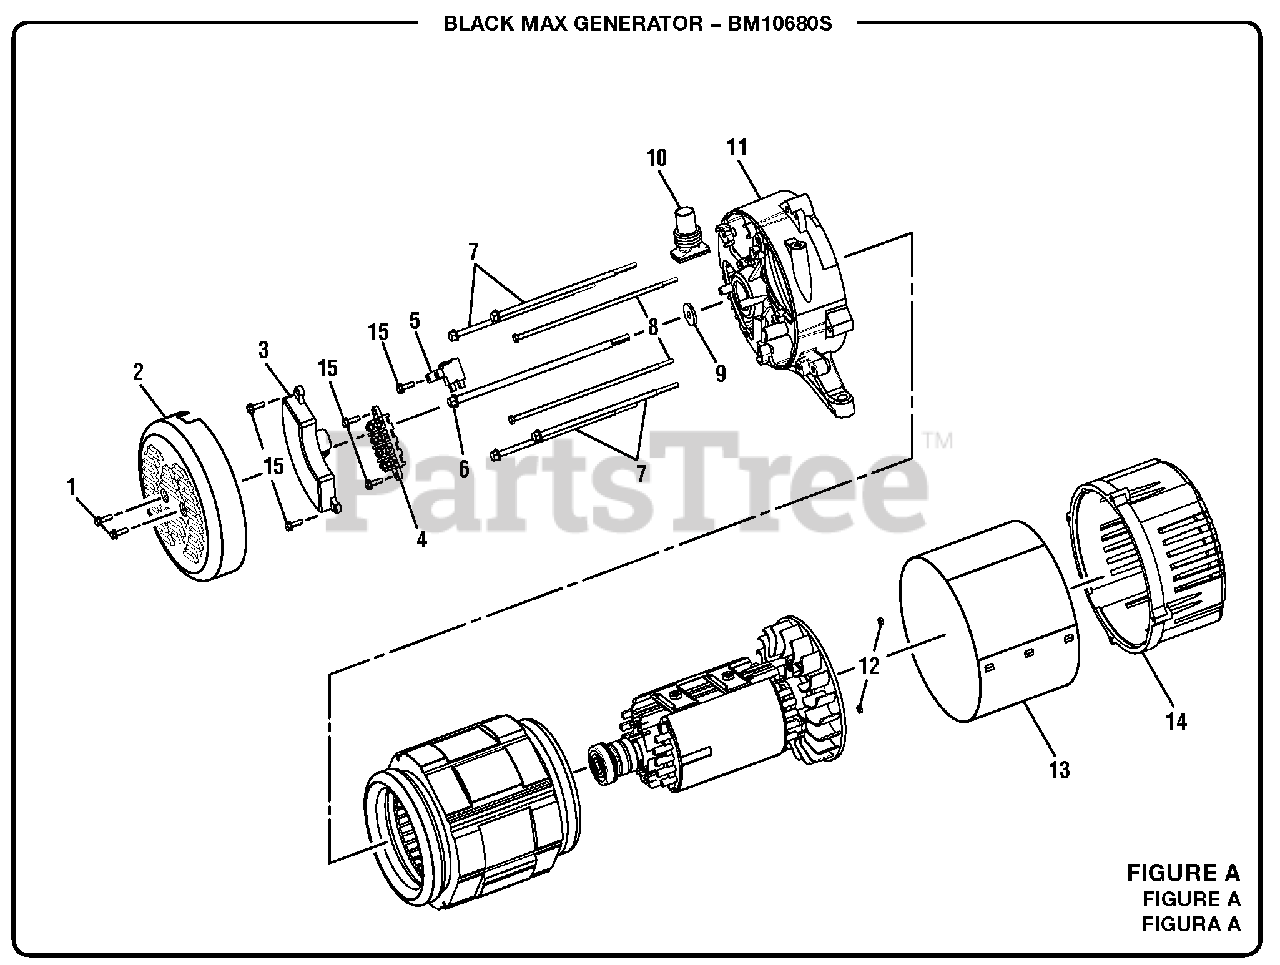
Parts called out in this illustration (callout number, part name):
1	Bolt (M5 x 12 mm, Hex Hd.)
2	Brush Cover
3	Automatic Voltage Regulator
4	Terminal Block
5	Brush Assembly
6	Bolt (5/16-24 x 235 mm, Hex Washer Hd.)
7	Bolt (M6 x 188 mm, Hex Washer Hd.)
8	Bolt (M5 x 210 mm, Hex Washer Hd.)
9	Washer (8 x 26 x 3t)
10	Rubber Boot
11	Bearing Housing
12	Hex Nut (M5)
13	Generator Head Cover
14	Adaptor Housing
15	Bolt (M5 x 16 mm, Hex Hd.)
